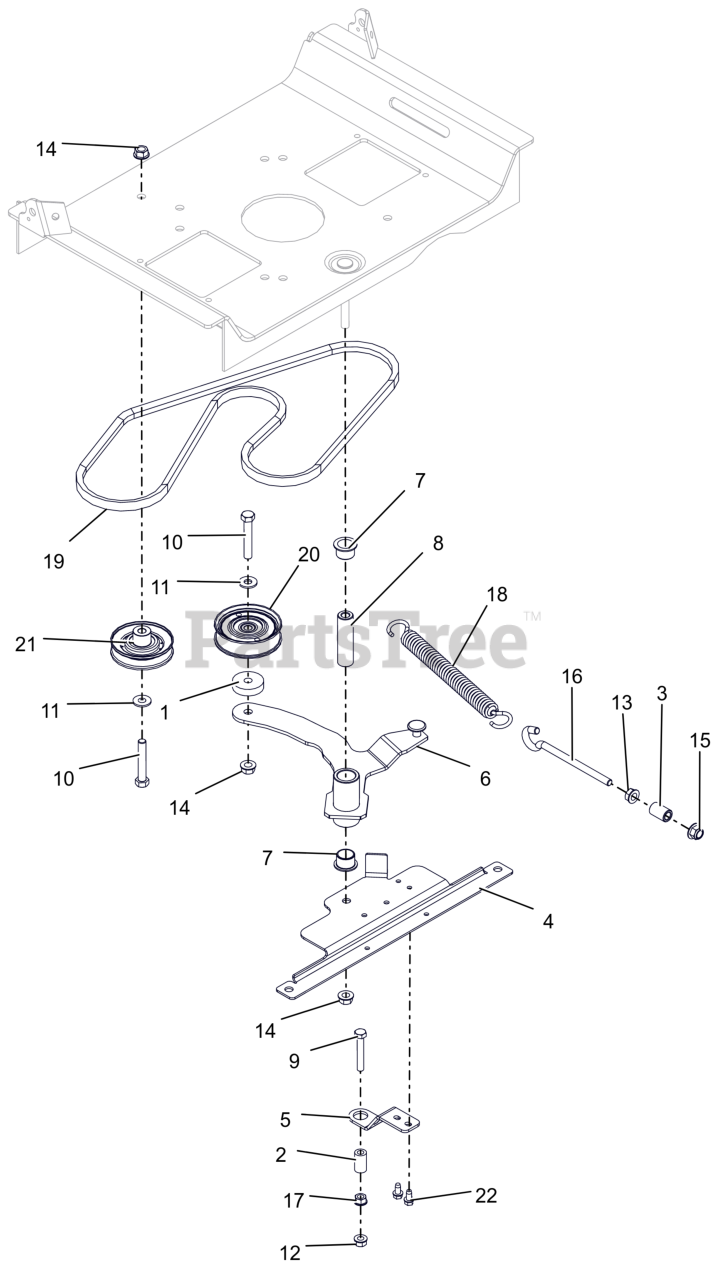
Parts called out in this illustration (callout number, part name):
1	SPACER, .39 X 1.50 X .380
2	SPACER, RUBBER 5/16 IDX1.0 LG
3	SPACER, .375X.625X.970 (PM)
4	BRKT-IDLER ATTACHMENT
5	BRKT, CLUTCH STOP (XL)
6	WLDMT,GRD DRIVE IDLER ARM-LGR
7	BSHG-FLG 0.75X0.875X.625X1.125
8	BUSHING, SLEEVE .38X.750X2.78
9	BLT, HEX .31-18X2.00 G5 ZCC
10	BLT,HEX .38-16X2.25 G5 ZCC
11	WSHR,FLT .375X.875X.083 ZCC
12	NUT-LK-TOP-FLG .312-18 GF ZCC
13	NUT, SPNLK-FLG .38-16 G5 ZCC
14	NUT-LK-TOP-FLG .38-16 ZC120
15	NUT,NYL-FLG .38-16 GF ZCC
16	BOLT,.38-16 X 4.25-.62 DIA EYE
17	NUT,SPNLK-FLG .31-18 G5 ZCC
18	SPRING, EXTENSION
19	V-BELT, A-RAW EDGE
20	IDLER, FLAT - 3.05" X .75"
21	IDLER, V-3.000 OD
22	SCR-TAP .25-20X.50 HWH ZCC
